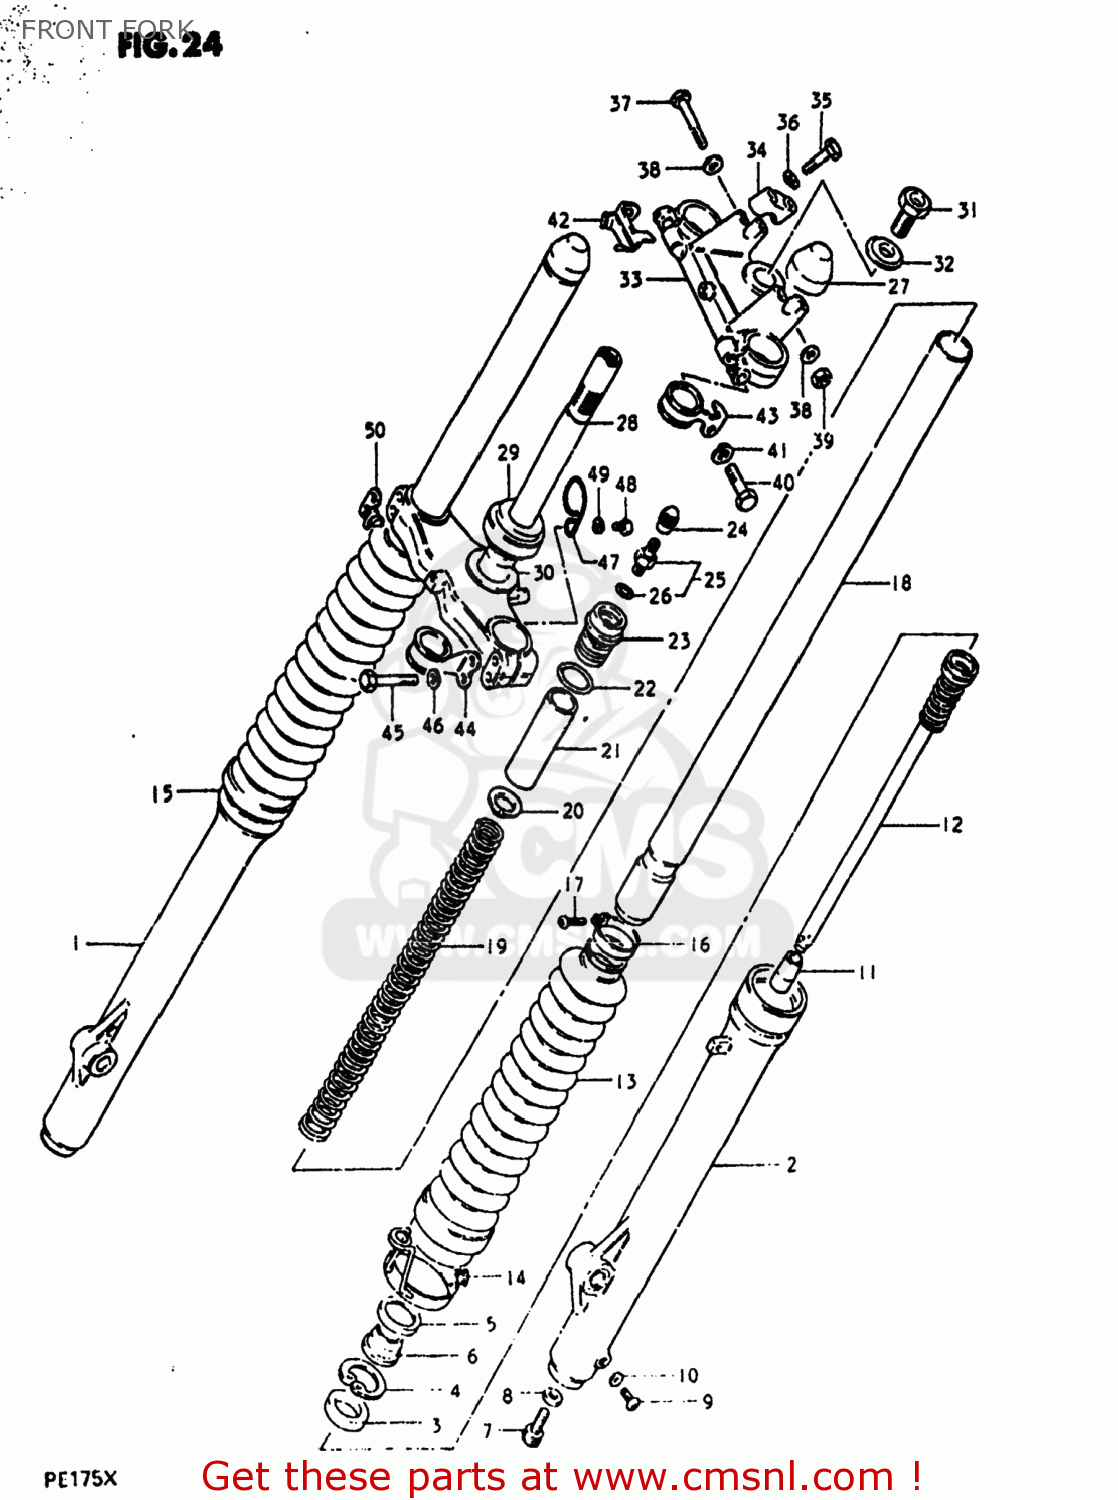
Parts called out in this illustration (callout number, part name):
1	TUBE,OUTER,RIGHT
2	TUBE,OUTER,LEFT
3	OIL SEAL,FRONT FORK
4	5
5	CASE,DUST SEAL
6	SEAL,DUST
7	BOLT,FORK CYLINDER(10X25)
8	GASKET (NAS)
9	SCREW
10	GASKET,DRAIN,PLUG (NAS)
11	PIECE,OIL LOCK
12	CYLINDER,FRONT FORK
13	BOOT
14	BAND,FORK COVER BOOT
15	BAND,FRONT FORK COVER
16	BAND,BOOT
17	SCREW
18	TUBE,FORK,INNER
19	SPRING
20	GUIDE,FRONT FORK SPRING C
21	SPACER,FRONT FORK SPRING
22	O RING
23	CAP,FORK INNER TUBE
24	CAP,VALVE
25	VALVE
26	O RING
27	CAP
28	STEM,STEERING
29	BEARING
30	WASHER,THRUST
31	BOLT
32	WASHER
33	HEAD,STEERING STEM
34	HOLDER,HANDLEBAR
35	BOLT
36	LOCK WASHER
37	BOLT 8X50
38	WASHER
39	NUT
40	BOLT
41	LOCK WASHER
42	BRACKET,TOOL FITTING,UPPER
43	GUIDE,CABLE
44	CLIP,CABLE
45	BOLT 8X45
46	LOCK WASHER
47	CLIP
48	SCREW
49	LOCK WASHER
50	BRACKET,TOOL FITTING,LOWER
